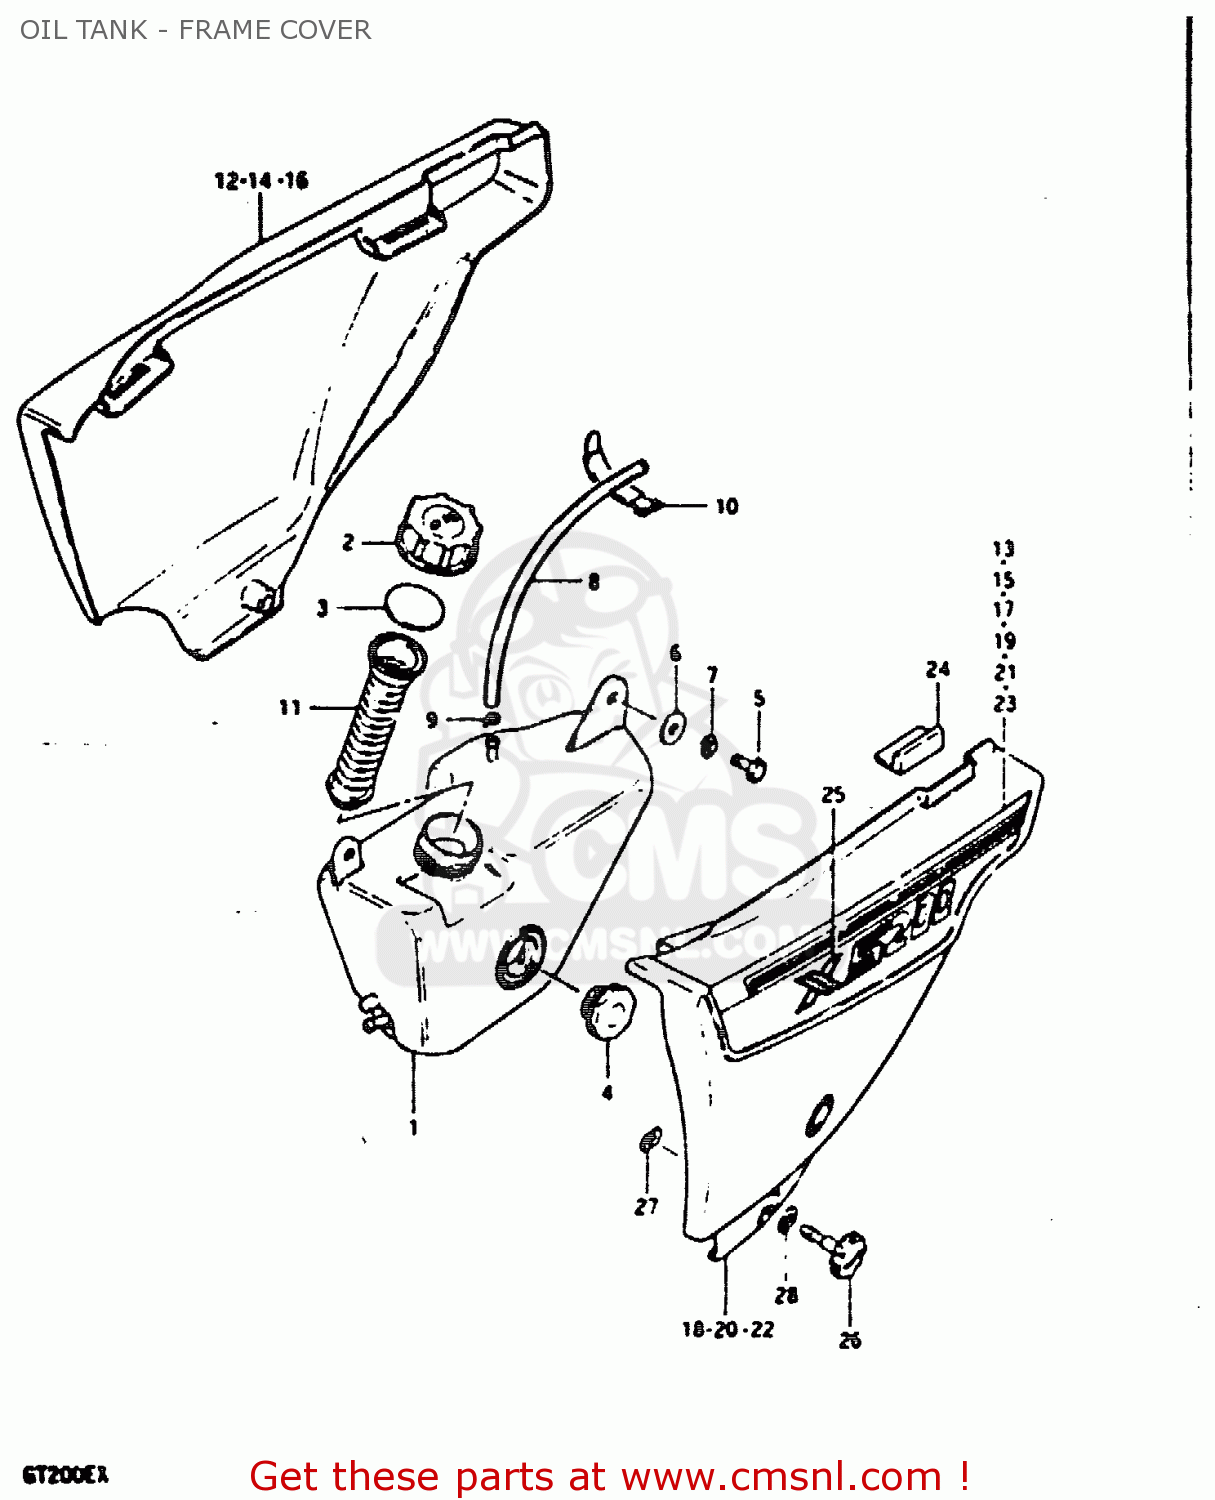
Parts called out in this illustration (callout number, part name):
1	TANK, OIL
2	CAP,OIL TANK
3	GASKET,OIL TANK CAP (NAS)
4	LENS SET,OIL LEVEL
5	BOLT, UPPER
6	WASHER
7	LOCK WASHER
8	HOSE
9	CLIP
10	CLAMP L:110
11	EXTENTION, OIL TANK INLET
12	COVER, FRAME RH (WHITE)
13	TAPE, RH
14	COVER, FRAME RH (BLUE)
15	TAPE, RH
16	COVER, FRAME RH (RED)
17	TAPE, RH
18	COVER, FRAME LH (WHITE)
19	TAPE, LH
20	COVER, FRAME LH (BLUE)
21	TAPE, LH
22	COVER, FRAME LH (RED)
23	TAPE, LH
24	CUSHION,FRAME COVER
25	EMBLEM, RH
26	KNOB
27	SCREW 6X12
28	WASHER
